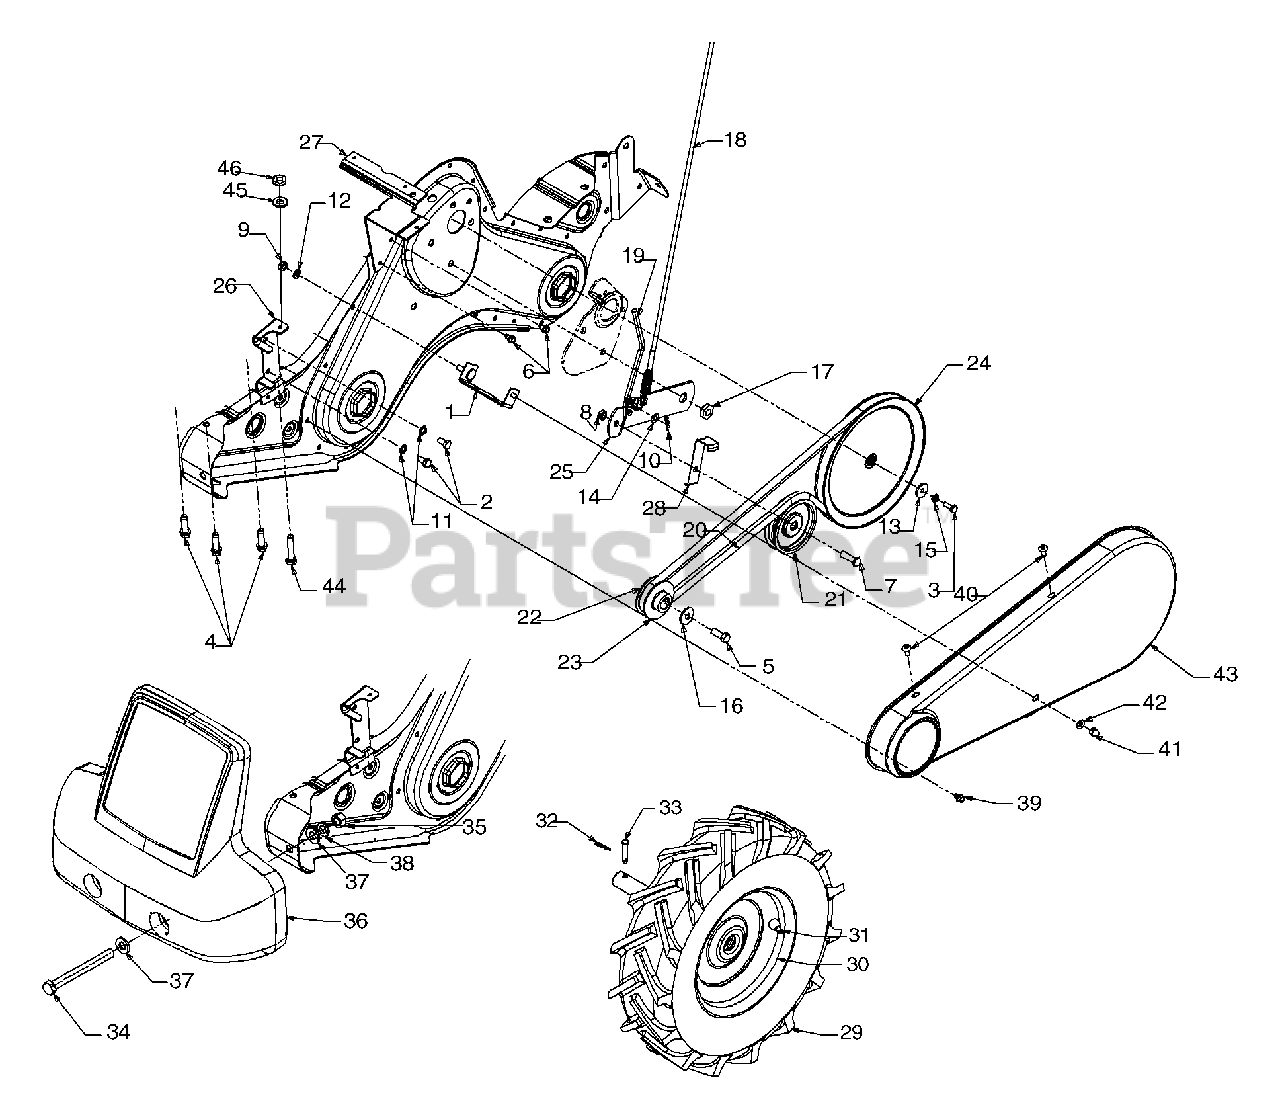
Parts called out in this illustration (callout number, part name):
1	Belt Cover Brkt. Ass'y
2	Hex Bolt 5/16-24 x .62" Lg.
3	Hex Bolt 1/4-28 x .75" Lg.
4	Hex Wash.TT-Sems Screw 3/8-16 x 1.250" Lg.
5	Hex Bolt 3/8-24 x 1.00
6	Hex Wash. Hd. S-Tap Scr.
7	Hex Cap Screw 3/8-16 x 1.25
8	Ctr. Lock Jam Nut 3/8-16
9	Hex Nut 5/16-18
10	Internal Cotter Pin
11	Hairpin Clip
12	L-Wash. 5/16" I.D.
13	Fl-Wash. 1/4 I.D. x .93 O.D.
14	Spring-Wash. .317 x .625 O.D. x .099
15	L-Wash. 1/4" I.D.
16	Bell-Wash. .396 x 1.140 x .095
17	Shld. Nut 7/16-20
18	Clutch Cable w/eyebolt
19	Idler Pulley Rod
20	Belt: 4L x 58.16 Lg.
21	Fl-Idler w/Flange 3.75" O.D.
22	Outer Engine Pulley Half
23	Inner Engine Pulley Half
24	Input Pulley
25	Idler Bracket
26	Belt Keeper Brkt.
27	Shift Cover Brkt.
28	Idler Belt Keeper
32	Clevis Pin
33	Internal Cotter Pin
34	Hex Bolt 1/2-13 x 5.00" Lg.
35	Hex Nut 1/2-13 Thd.
36	Counterweight
37	Fl-Wash. .510" I.D. x 1.0" O.D.
38	L-Wash. 1/2" Lg.
39	Hex Screw 1/4-20 x .375" Lg.
40	Screw 1/4-14 x .625" Lg.
41	Acorn Lock Nut
42	Fl-Washer 1/4 x .620" Lg.
44	Hex Bolt 5/16-18 x 1.50" Lg.
45	Bell-Wash. .340 I.D. x .872 O.D.
46	Nut:Hex 5/16-18
